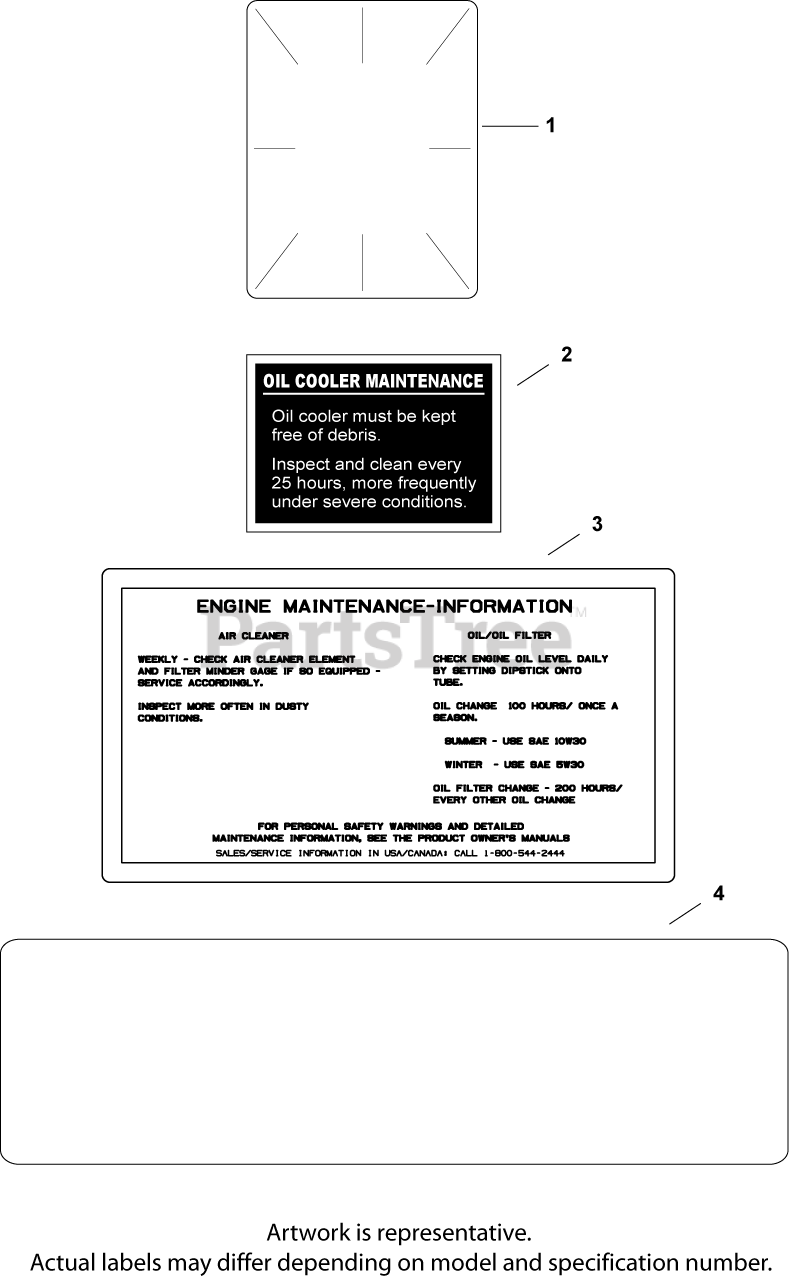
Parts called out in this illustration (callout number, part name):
1	DECAL, CLEAR LAMINATE USE 25 113 70-S
2	DECAL, OIL COOLER - (#DSC)
3	DECAL, AIR CLEANER - (#DSC)
4	DECAL, 27 HP
